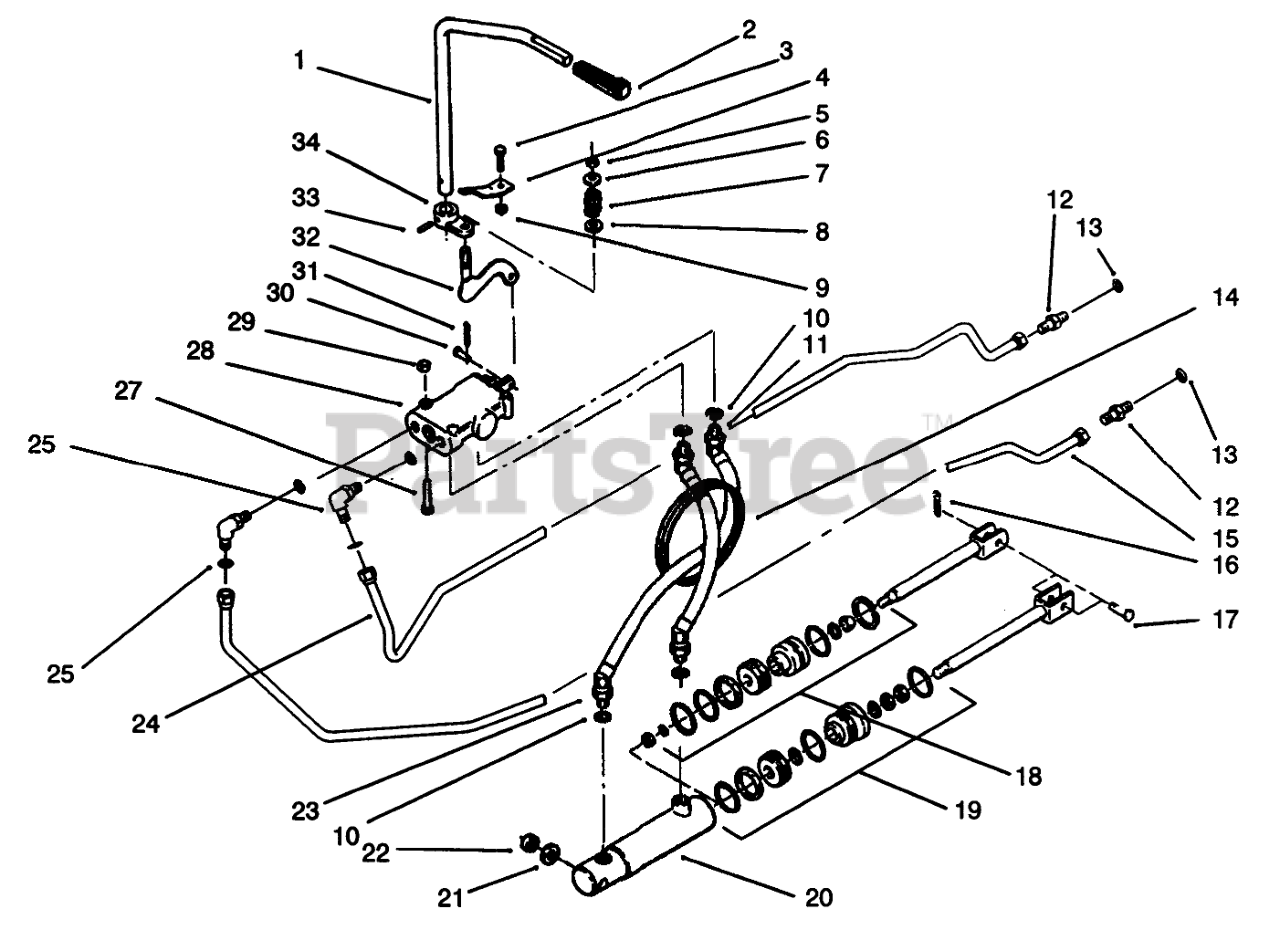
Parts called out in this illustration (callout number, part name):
1	ROD-LIFT CONTROL
2	KNOB-HYDRAULIC LIFT
3	SCREW-HH
4	BRACKET-CONTROL R B
5	NUT-LOCK, NI
7	SPRING
8	SCREW-HH
9	NUT-LOCK, NI
10	O RING
11	Hose ASM-Hydraulic
12	Fitting-Straight Adapter
13	0-Ring
14	GROMMET
15	FACE PLATE - INSTRUMENT
16	PIN-COTTER
17	CLEVIS PIN
18	S/A O-RING&GASKET AS
19	S/A 108872 HYD CYL
20	Cylinder-Hydraulic (Incl. Ref. #18-19)
21	SPACER-WORM SHAFT
22	WASHER
23	Hose ASM-Hydraulic
24	TUBE-HYD PRESSURE
25	ELBOW
27	SCREW-HH
28	Valve-Hydraulic (Incl.Ref. #30-31)
29	NUT-LOCK, NI
30	Pin
31	Cotter Pin
32	WLDMT-LIFT BAR
34	ARM-CONTROL
